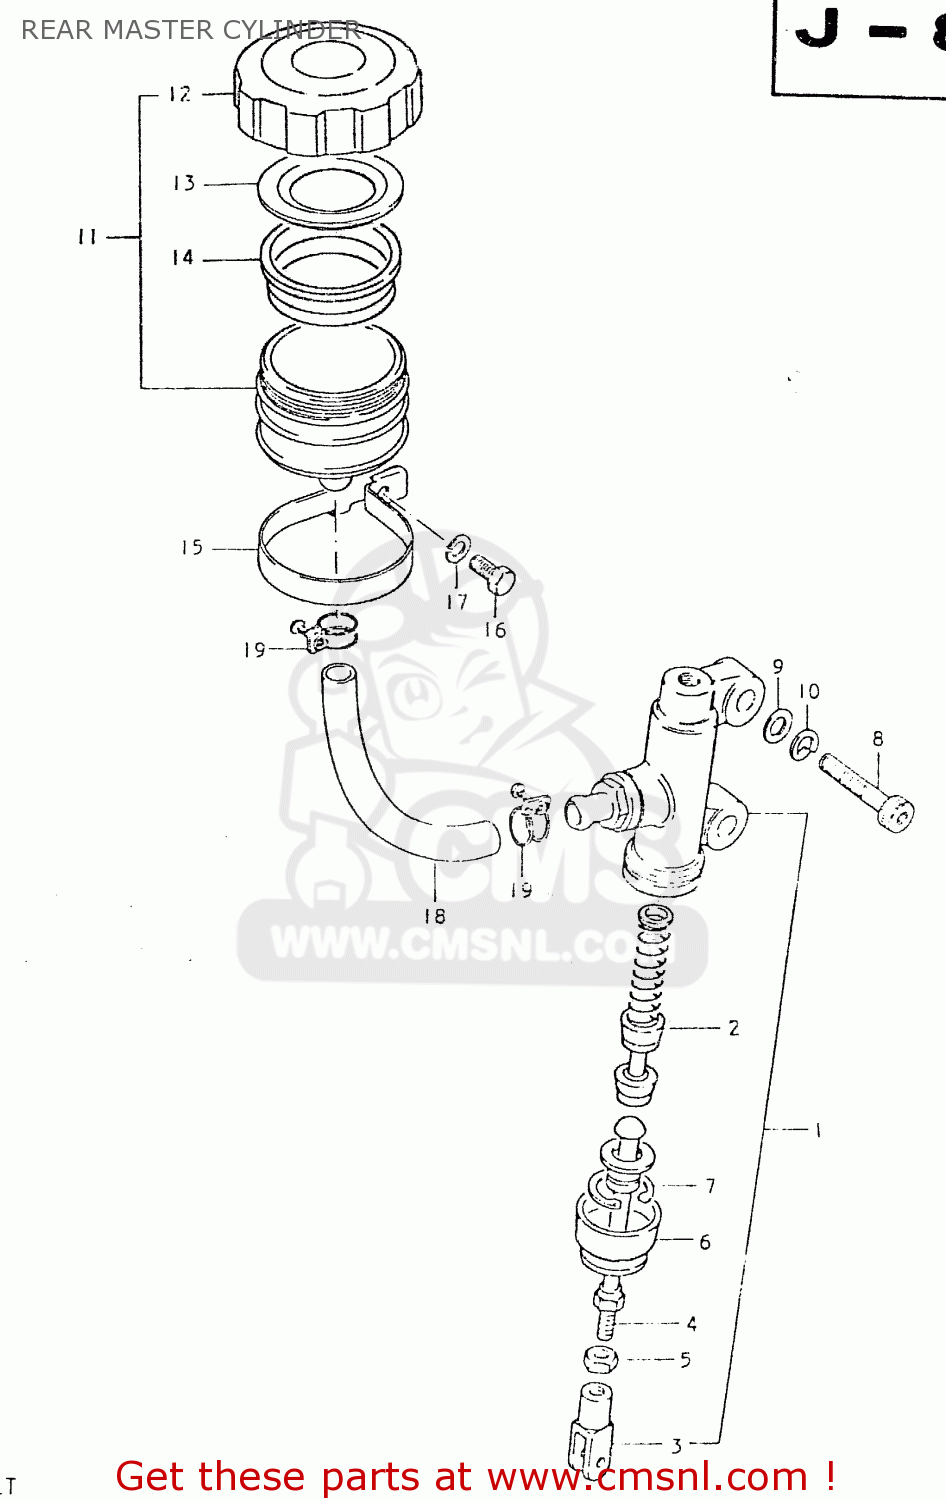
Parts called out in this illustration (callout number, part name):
1	CYLINDER ASSEMBLY,REAR MASTER
2	PISTON/CUP SET
3	YOKE
4	ROD,PUSH
5	NUT
6	BOOT
7	CIRCLIP
8	BOLT (8X30)
9	LOCK WASHER
10	WASHER
11	TANK ASSEMBLY,RESERVOIR
12	CAP
13	PLATE,DIAPHRAGM
14	DIAPHRAGM
15	CLAMP
16	BOLT, UPPER
17	LOCK WASHER
18	HOSE,RESERVOIR TANK
19	CLAMP
